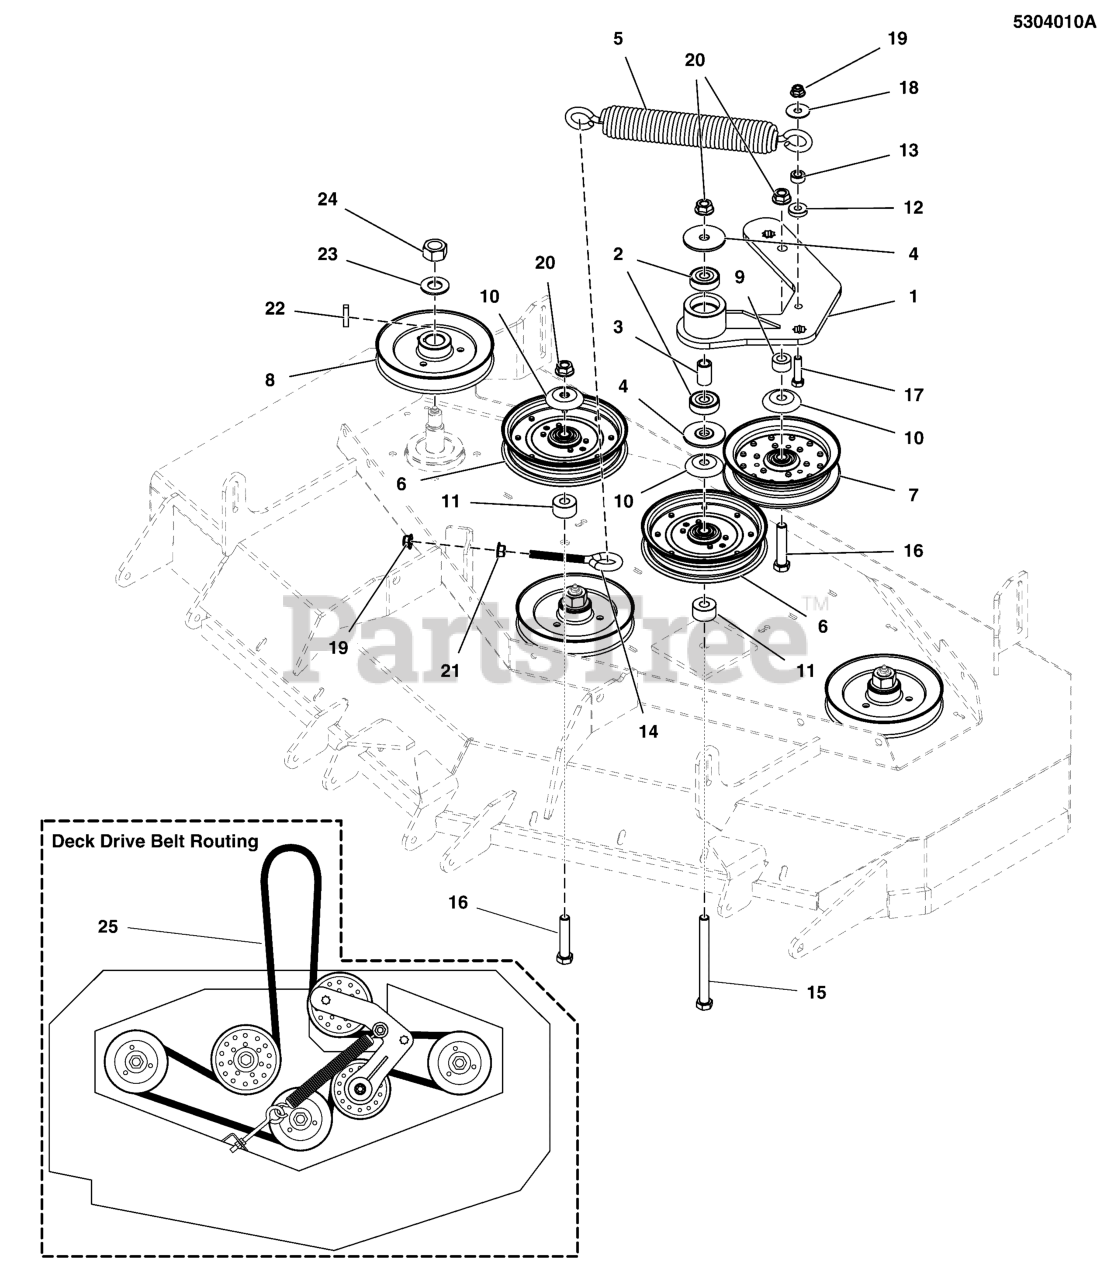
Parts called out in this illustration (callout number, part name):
1	WELD, IDLER ARM,CUTTER DECKS - BLK
2	BEARING, 6203-1/2", SEALED
3	SPACER, .51 X .75 X 1.22, PM CZ
4	SPACER, IDLER ARM, 1/2 X 2.25
5	SPRING, EXT, 1.5ODX12.25X.234WIRE BLK
8	PULLEY, 5.926 OVER BALL
9	SPACER, .52 X 1.00 X .56, PM, CZ
10	SHIELD, PULLEY BEARING, CZ
11	SPACER, .52 X 1.25 X .70, PM, CZ
12	SPACER, .39 X 1.00 X .25, PM, CZ
13	SPACER, .39 X .75 X .38, PM, CZ
14	EYE BOLT, 3/8-16 X 5, 2.88THRD, 1EYE, CZ
15	BOLT, 1/2-13 X 5-1/2 GD5 CZ
16	BOLT, 1/2-13 X 2-1/2" GD5 CZ
17	BOLT, 3/8-16 X 1-1/2" GD5 CZ
18	WASHER-3/8 FENDER
19	NUT, 3/8-16 HEX NYLOCK FLANGE
20	NUT, Hex Flange, Nylock, 1/2-13
21	NUT, 3/8-16 HEX SERRATED FLANGE
22	KEY, 1/4 SQ X 1-1/4
23	WASHER, 3/4 BELLEVILLE
24	NUT, 3/4-16 HEX
25	BELT, 5V, 182.00"EL, LRG ARAMID, WRP, RC
